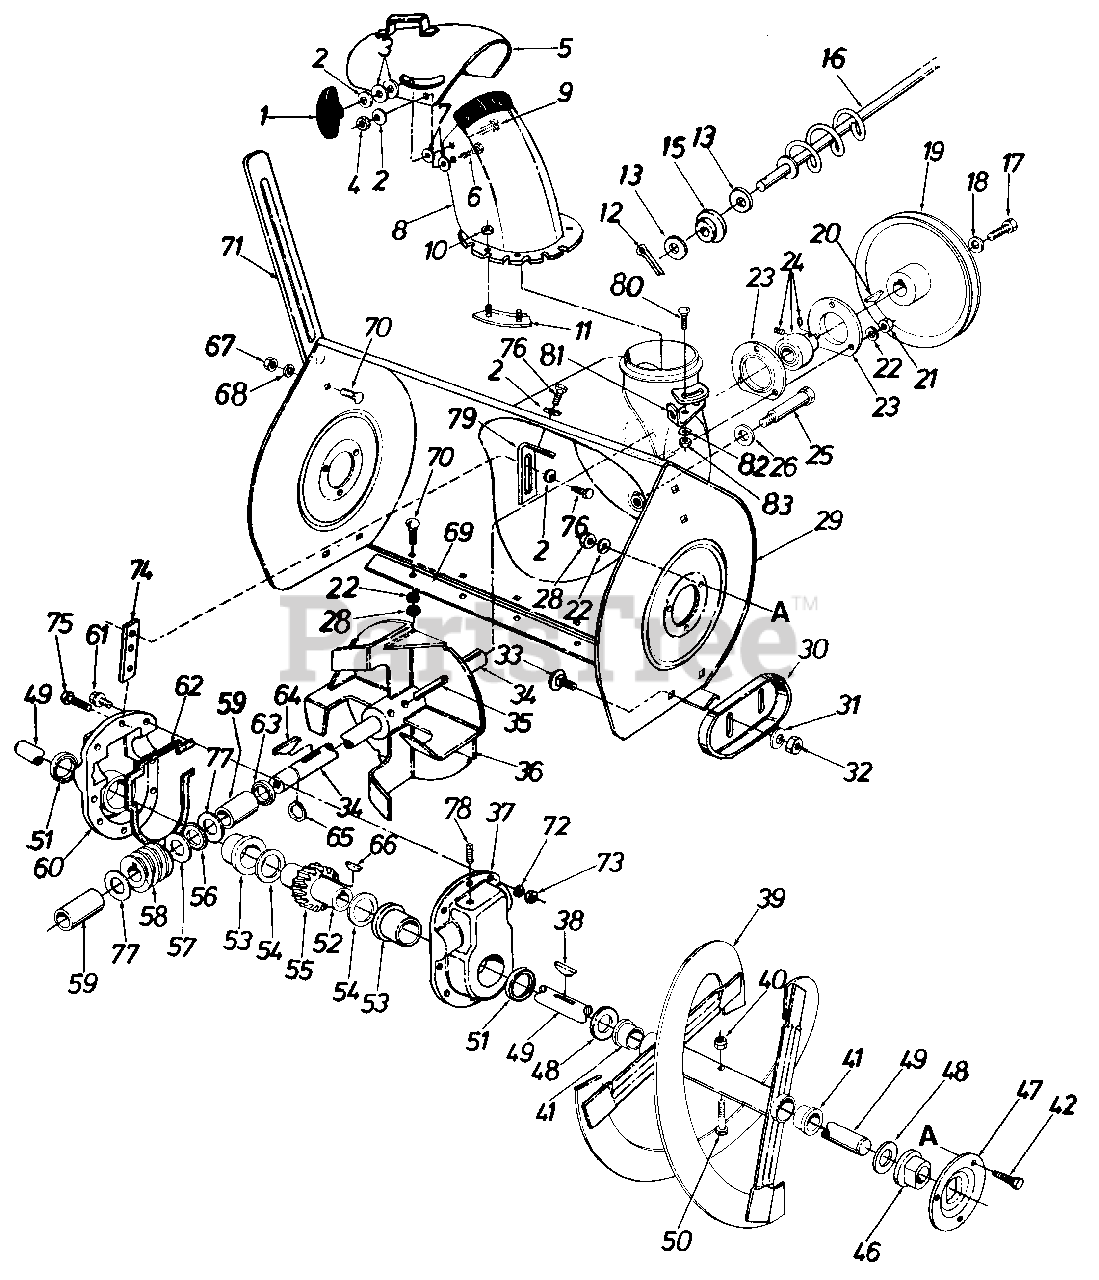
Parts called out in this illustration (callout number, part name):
1	Hand Knob Ass'y.
2	Bell-Wash. .345 I.D. x .88 O.D. x .060
3	Fl. Wash. .312 I.D. x 1.125 O.D. x .125
4	Hex Cent. L-Nut 5/16-18 Thd.
5	Top Chute Ass'y.
6	Carr. Bolt 5/16-18 x .62" Lg.
7	Fl-Wash. .53 I.D. x 1.25 O.D. x . 1 00
8	Chute Ass'y.
9	Carr. Bolt 5/16-18 x 1.00" Lg.
10	Hex Cent. L-Nut l/2-20 Thd.
11	Chute Flange Keeper Ass'y.
12	Cotter Pin
13	Fl-Wash. .385" I.D. x .62" O.D.
15	Bushing
16	Chute Crank Ass'y.
17	Hex L-Scr. 5/16-18 x .88" Lg.
18	Bell-Wash. .345 I.D. x .88 O.D. x .060
19	V-Pulley .875 I.D. x 10.12 O.D.
20	#9 Hi-Pro Key 3/16 x 3/4" Dia.
21	Hex Nut 5/16-18 Thd.
22	L-Wash. 5/16" Scr.
23	Bearing Hsg. Self Aligning Brg.
24	Self Aligning Brg. .875 I.D.
25	Stud 3/8-16 X 2.75" Lg.
26	Bell-Wash. .400 I.D. x .88 O.D. x .060
28	Hex Nut 5/16-18 Thd.
29	Blower Hsg. Ass'y.
30	Slide Shoe
31	Bell-Wash. .400 I.D. x .88 O.D. x .060
32	Hex Jam Nut 3/8-16 Thd.
33	Carr. Bolt 3/8-16 x .62" Lg.
34	Blower Axle
35	Spring Pin Spiral 5/16" Dia. x 1.75" Lg.
38	#91 Woodruff Key 1/4" X 3/4" Dia.
39	33" Spiral Ass'y. L.H.
40	Hex Ins. L-Nut 5/16-18 Thd.
41	Plastic Bushing
42	Hex Sems Scr. 5/16-18 x .75" Lg.
46	Flange Brg. w/Flats 1.0" I.D.
47	Bearing Hsg. Spiral Hsg.
48	Fl-Wash. 1.06 I.D. x 1.75" O.D. x .100
49	Spiral Axle 33"
50	Hex Bolt 5/16-18 x 1.75" Lg.
51	Oil Seal 1.50" I.D.
52	Worm Gear Shaft
53	Flange Brg. 1.503 I.D.
54	Fl-Wash. 1.50 I.D. x 2.00 O.D. x .030
55	Double Threaded Worm Gear
56	Thrust Brg. .88 I.D. x 1.44 O.D. x .078
57	Fl-Wash. .88 I.D. x 1.40 O.D. x . 1 50
58	Double Threaded Worm L.H.
59	Sleeve Brg. .875 I.D.
60	Complete Gear Hsg. Half R.H.
61	Hex Scr. 5/16-18 x 1.00" Lg.
62	Gasket
63	Oil Seal .875" I.D.
64	#9 Hi-Pro Key 3/16 x 3/4" Dia.
65	Snap Ring for .875" Dia. Shaft
66	#91 Woodruff Key 1/4 X 3/4" Dia.
67	Hex Nut 5/16-18 Thd.
68	L-Wash. 5/16" Scr.
70	Carr. Bolt 5/16-18 x .62" Lg.
71	Drift Cutter
72	Wave Wash. 5/16" Scr.
73	Hex Ins. L-Nut 5/16-18 Thd.
74	Gear Hsg. Support Brkt.
75	Hex Scr. 5/16-18 x 1.25" Lg.
76	Hex Wash. Hd. Self-Tap Scr. 5/16-18 x .75" Lg.
77	Fl-Wash. .88 I.D. x 1.40 O.D. x . 150
78	Filler Plug
80	Carr. Bolt 5/16-18 x .75" Lg.
82	Bell-Wash. .345 I.D. x .88" O.D.
83	Hex Nut 5/16-18 Thd.
